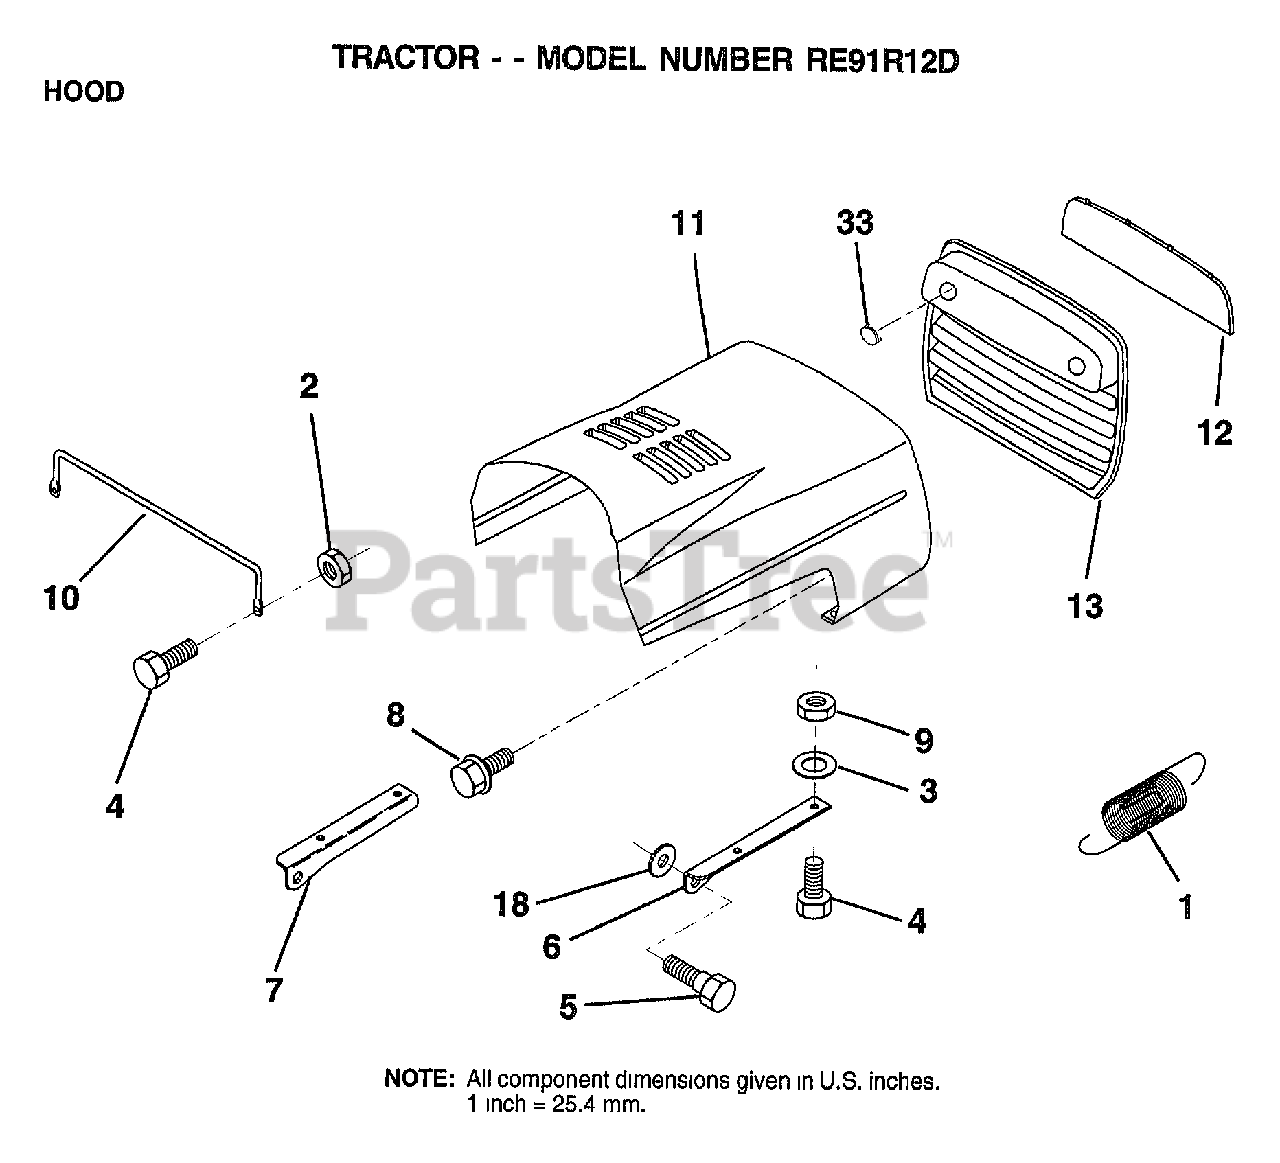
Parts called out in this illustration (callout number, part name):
1	EXT SPRING
2	NUT
3	WASHER
5	BOLT.SHLD.5/16-18
6	BRKT HOOD RH
7	BRKT HOOD LH
8	"SCREW,HWHD.HI-LO#13-16X3/4"
9	NUT
10	"BRACE,HOOD"
11	HOOD
12	LENS
13	GRILL
18	WASHER
